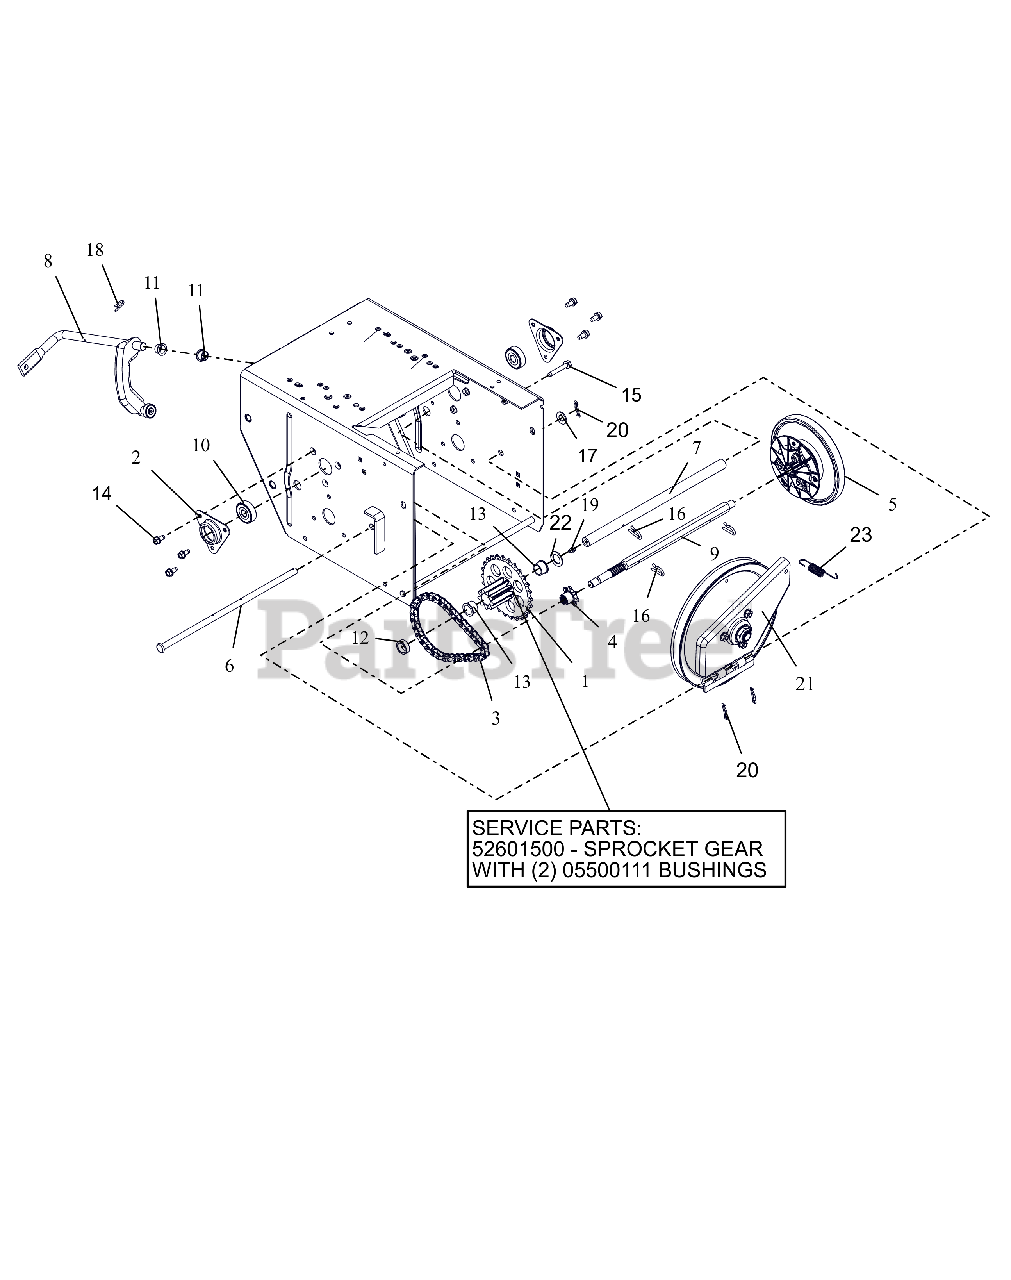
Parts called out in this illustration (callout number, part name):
1	PINION & SPROCKET
1	PINION & SPROCKET W/BUSHINGS
2	FLANGE, BEARING
3	CHAIN - #41, 32 PITCHES
4	SPROCKET, PINION 7T W/SPLINE
5	DISC, FRICTION DRIVE-ASSEMBLY
6	PIN, PIVOT
7	SHAFT, PINION
8	ARM, SHIFT - ASSEMBLY
9	SHAFT, HEX
10	BRG-BALL .437X1.375X.437
11	BUSHING, POLYLINER-.50 SPLIT
12	BSHG-SLV, .635X.880X.305
13	BSHG-FLG .625X.750X.500X.875
14	SCR-TAP .25-20X.50 HWH ZCC
15	SCR,TAP .25-20X1.50 HWH TR ZCC
16	PIN, SPRING CLIP
17	WSHR,FLT .406X.812X.065 ZCC
18	CLIP, SPRING
19	ZERK,FITTING .25X.125 DRIVE IN
20	PIN, HAIR #225 .072X1.09
21	PLATE, SWING ASSEMBLY-DEEP
22	WSHR, FLT .630X1.005X.062 ZCC
23	SG-TENS .048X.50X2.8
